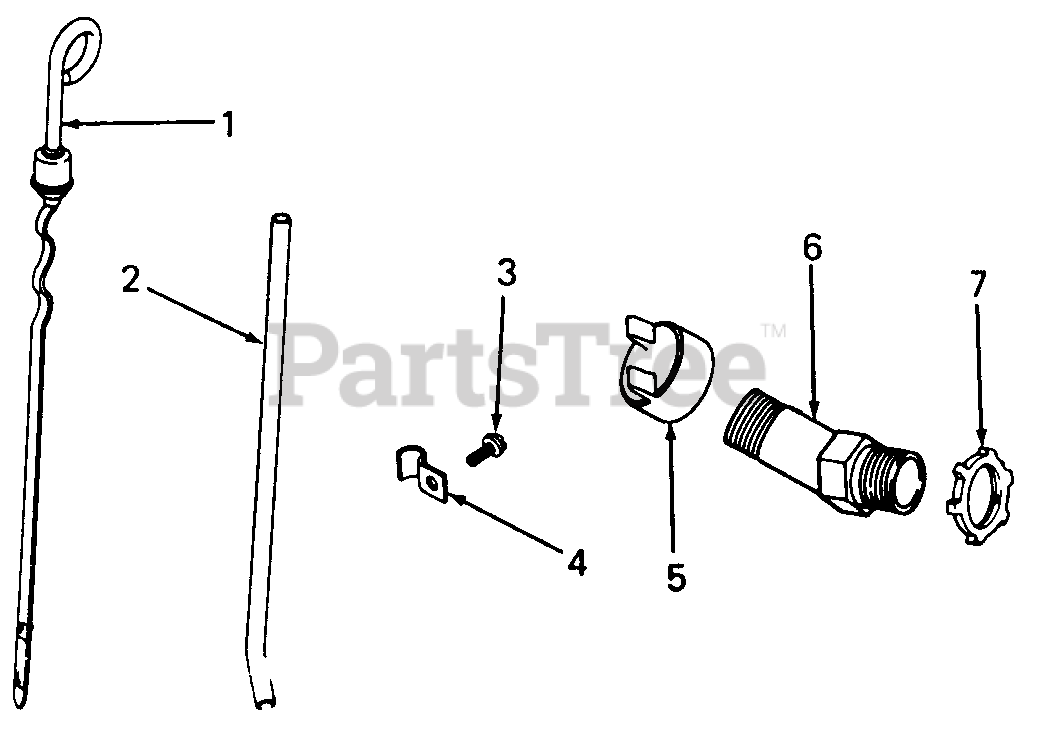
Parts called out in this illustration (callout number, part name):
1	Dipstick, Oil Level, 11-5/16
2	Tube, Oil Level
3	Screw, Hex Wash Hd, #10-32 X .37 Lg
6	Tube, Oil Fill
7	Nut, Lock, 3/4 IP
